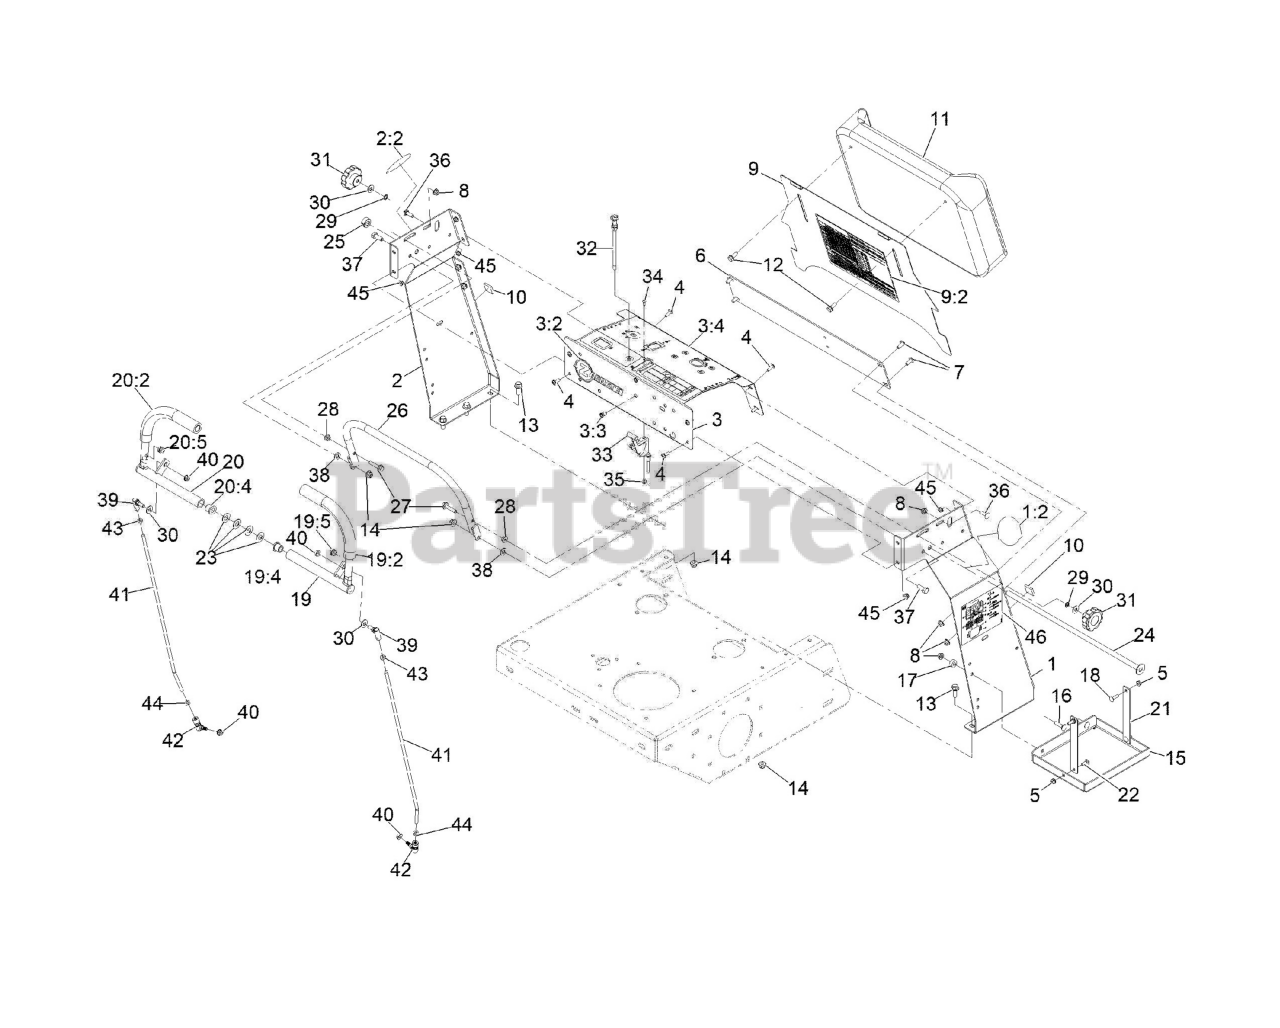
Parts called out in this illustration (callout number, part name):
1	PANEL-TOWER, LH
1:2	Decal-Z-Logo
2	PANEL-TOWER, RH
2:2	Decal-Z-Logo
3	PANEL-CONTROL
3:2	DECAL-Z-AERATE LOGO
3:3	Nut-Clinch, Hex
3:4	Decal-Control Panel
4	Screw-Hsbhf
6	PLATE-FACE
7	SCREW-PTH
8	NUT-HF, NI
9	PLATE-PAD,KNEE
9:2	Decal-Spray Chart
11	PAD-KNEE, Z-LOGO
12	SCREW-HHF
13	SCREW-HHF 3/8-16 X 1
14	NUT-HF, NI
15	TRAY-BATTERY
16	Bolt-Carriage 5/16-18 X 1 1/4
18	SCREW-CARR
19	HANDLE-CONTROL, LH ASM
19:2	GRIP-CONTROL, MOTION
19:4	Bushing,Flange,0.50 ID,0.75 OD
19:5	Grommet-Rubber
20	HANDLE-CONTROL, RH ASM
20:2	GRIP-CONTROL, MOTION
20:4	Bushing,Flange,0.50 ID,0.75 OD
20:5	Grommet-Rubber
21	Strap-Battery
22	BOLT-CARR
23	WASHER-PIVOT
24	Rod-Pivot, Joy Stick
26	Bar-Speed [red]
27	SCREW-HHF
28	Nut-Flange
29	Washer-Lock
30	FLAT WASHER, 5/16 NOM,ST
31	KNOB-FLUTED
32	CABLE-CHOKE
33	CABLE-THROTTLE
34	Screw-HSBH
35	Nut-Hex Flange
36	SCREW-CARR
37	SCREW-HH
38	WASHER-FLAT
39	Balljoint-SS
40	Nut-HHF
41	ROD-CONTROL
42	Ball Joint-Quick Disconnect, SS
43	Nut-Hex
44	Nut-Hex
45	Nut-Hex Flange
46	Decal-Service Aid
